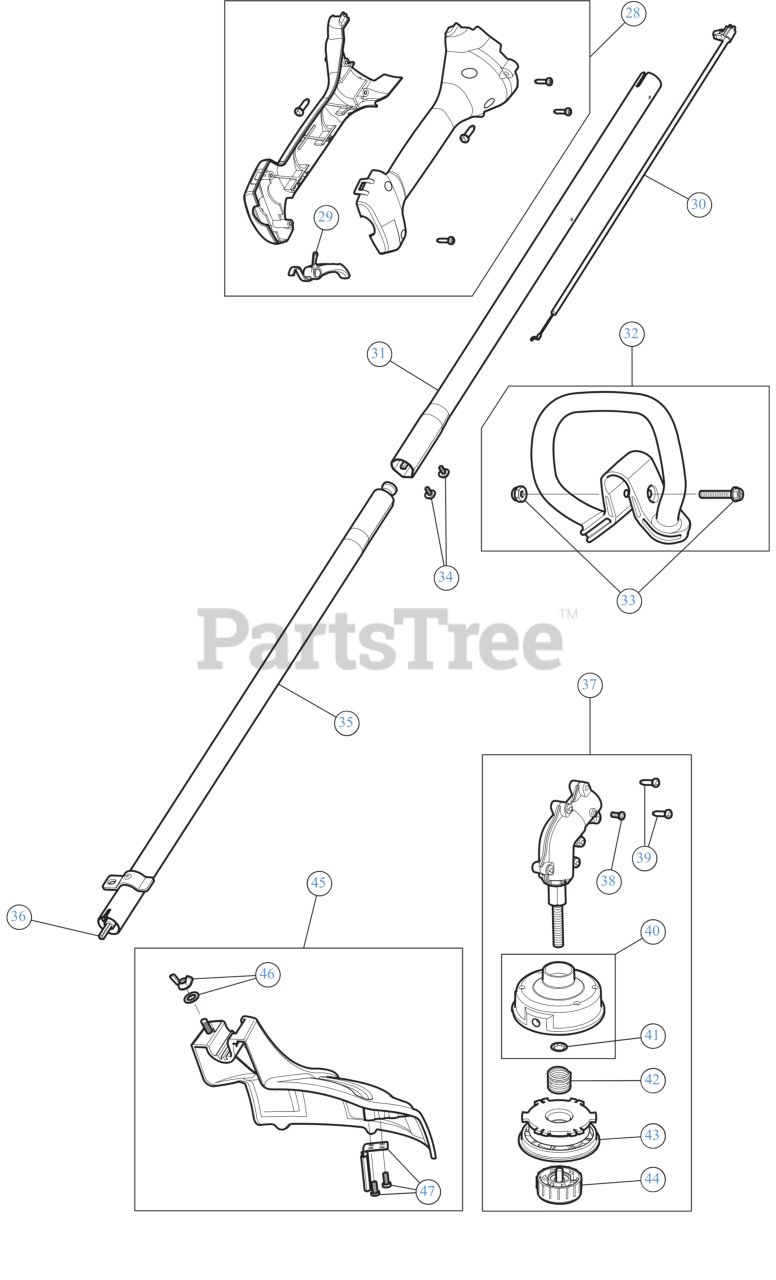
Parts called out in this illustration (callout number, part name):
28	THROTTLE GRIP ASSEMBLY
29	THROTTLE TRIGGER
30	THROTTLE CABLE
31	UPPER BOOM ASSEMBLY
32	D-HANDLE
33	BOLT 1/4-20X1 1/2
34	SCREW 8-32X3/8
35	LOWER BOOM ASSEMBLY
36	FLEX SHAFT
37	GEARBOX
38	SCREW, 8-32 x .312 P
39	SCREW #
40	OUTER REEL W/RETAINING RING
41	RETAINER .625 OD 2
42	SPRING-SPOOL
43	REEL-INNER SPOOL
44	BUMP HEAD KNOB ASSEMBLY
45	GUARD & BLADE ASSEMBLY
46	BLADE GUARD MOUNTING HARDWARE
47	BLADE ASSEMBLY W/HDW
